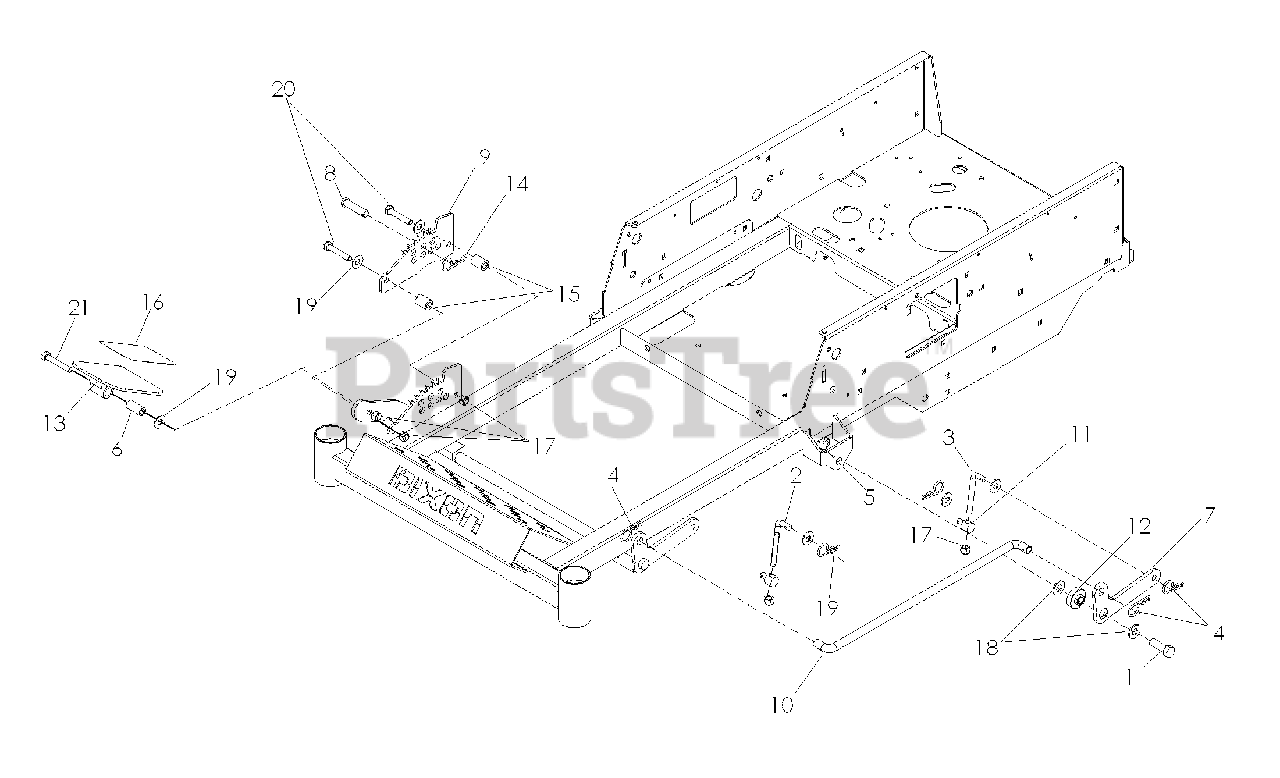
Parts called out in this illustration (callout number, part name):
1	HCS 1/2-13 X 1-1/2 GR 5 ZD
2	L ROD 3-7/8
3	L-ROD 3.5
4	PIN, COTTER 1 3/4
5	NUT 1/2-13 HEX JM NYL
6	BUSHING
7	REAR LIFT LINK
8	CLEVIS PIN 1/2 X 2 LG
9	LIFT QUADRANT (DK BLUE)
10	LINK DECK LIFT
12	IDLER SPACER
13	FOOT PEDAL (PLATED)
14	STAINLESS COTTER
16	FOOT PAD
17	NUT 3/8-16 NYLOC
18	WASHER 1/2" FLAT
19	WASHER 3/8 FLAT
20	HCS 3/8C X 2
21	HCS 3/8C X 2 1/4
